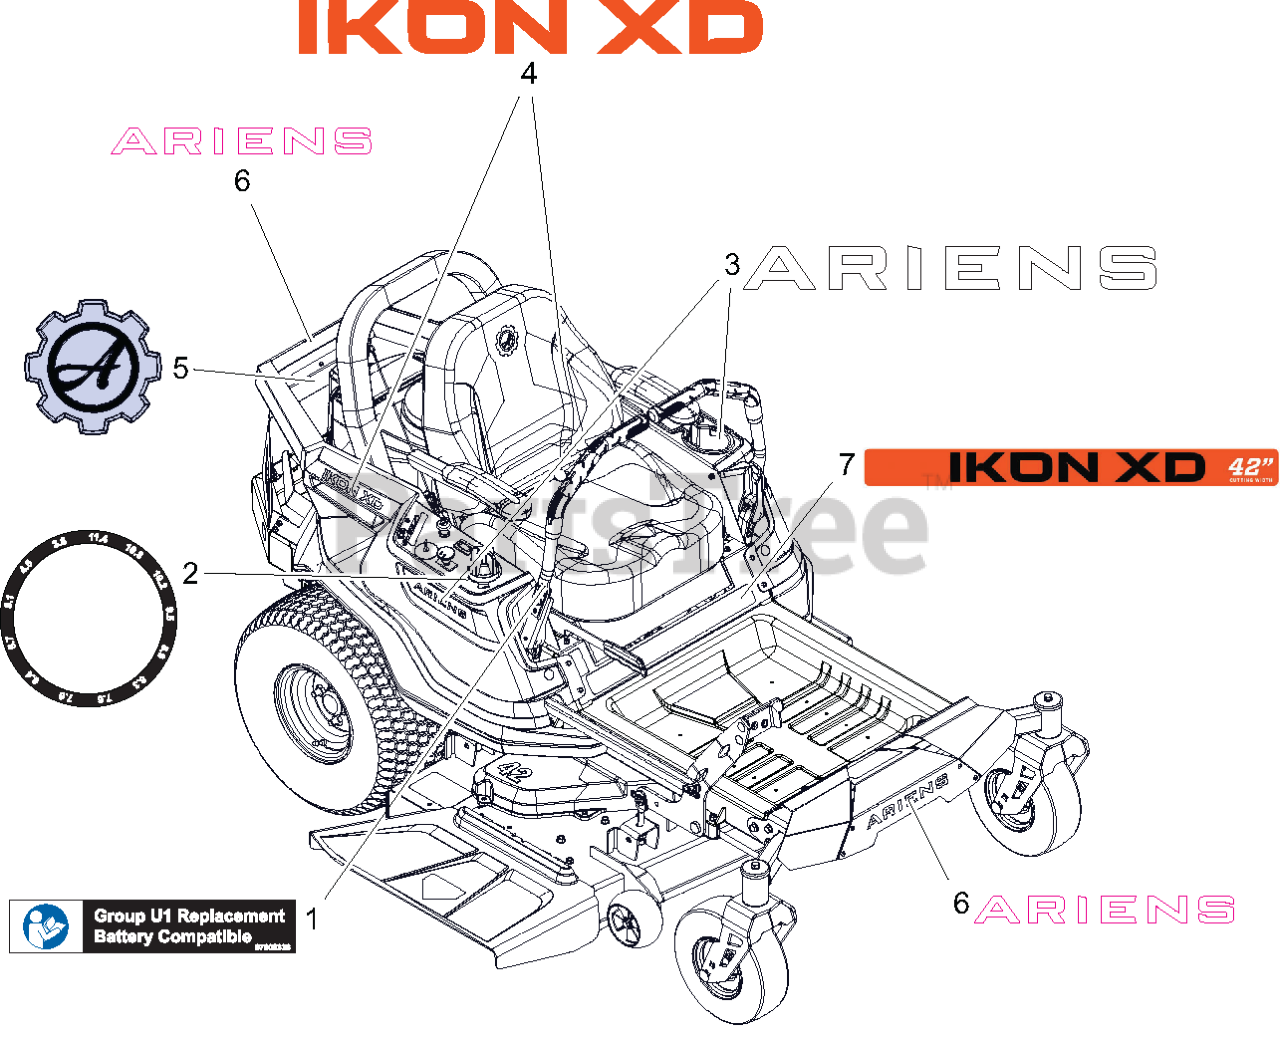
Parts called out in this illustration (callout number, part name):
1	DECAL, U1 BATTERY REPLACEMENT
2	DECAL, CUT HEIGHT - IKON CE
3	DECAL, ARIENS (6.50")
4	DECAL, FENDER - IKON XD
5	DECAL- ARIENS GEAR BADGE
6	DECAL - ARIENS 9.625"
7	DECAL, IKON XD - 42
